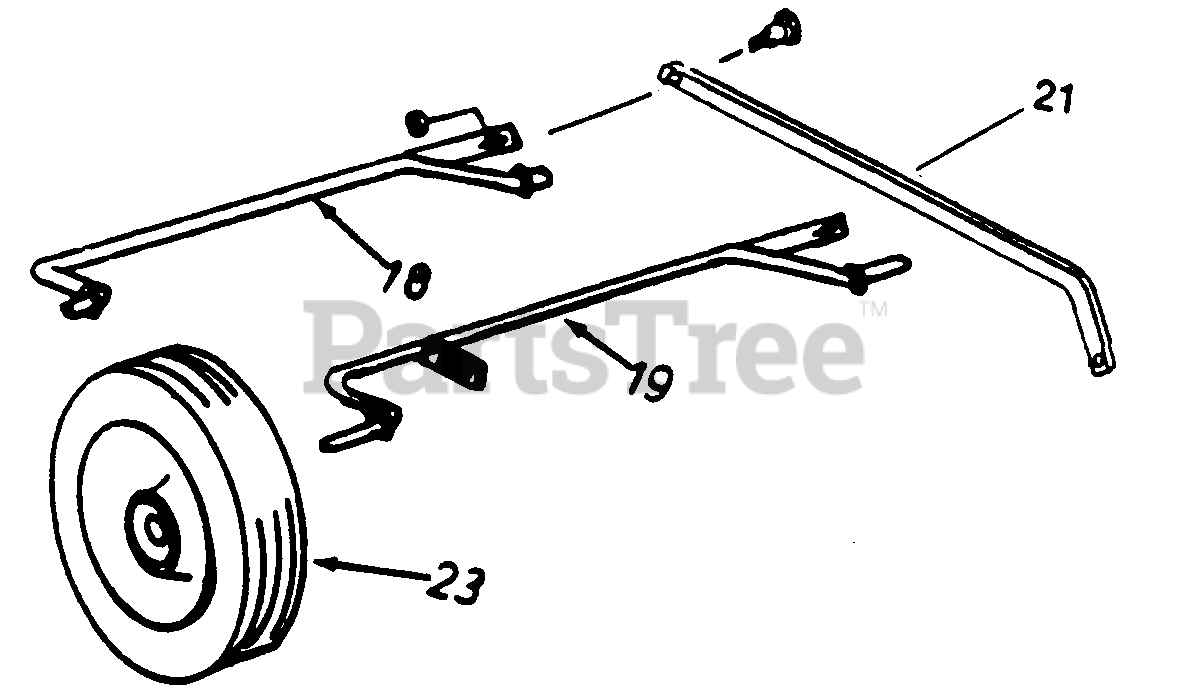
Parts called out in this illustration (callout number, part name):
18	Rear Axle Assembly
19	Front Axle Assembly
23	Wheel Ass'y. Comp.
